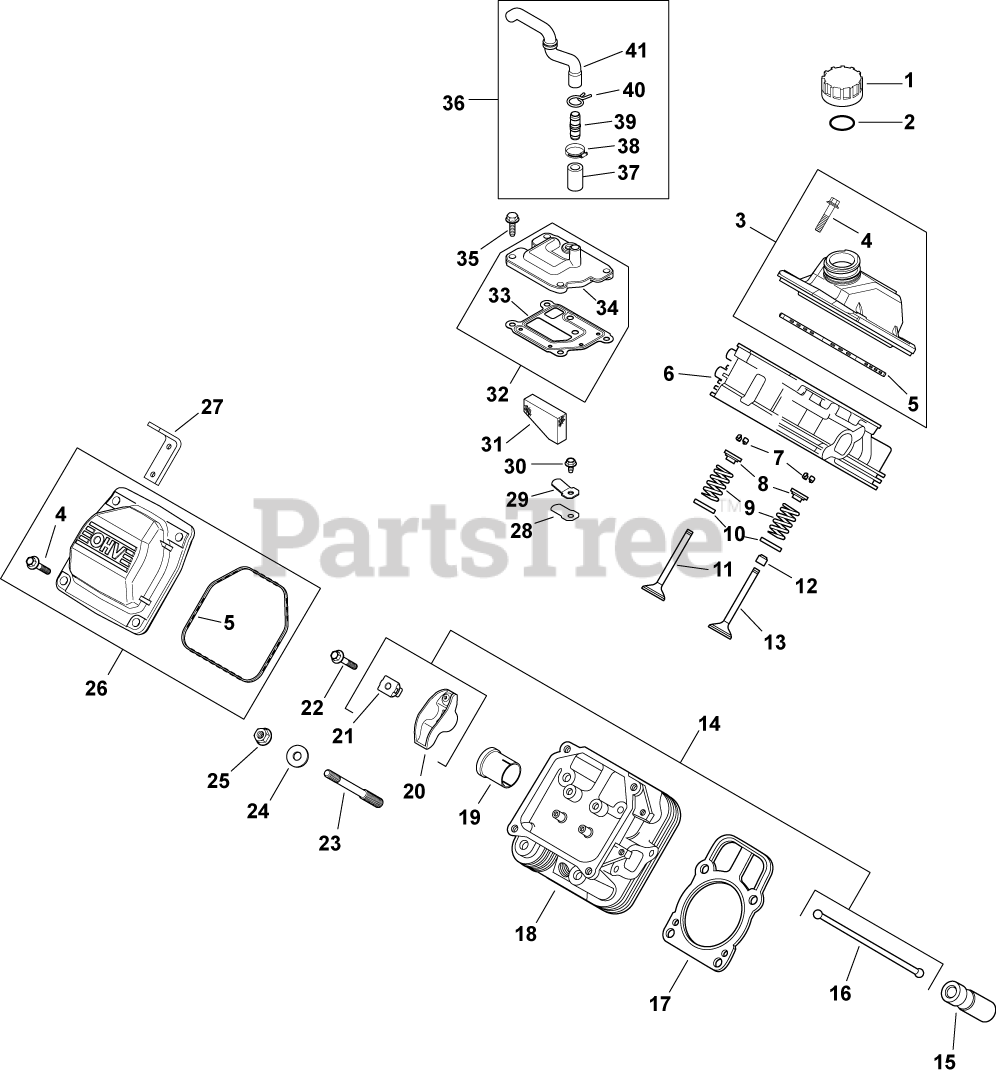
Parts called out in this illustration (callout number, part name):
1	KIT, OIL FILL CAP (YELLOW)
2	O-RING, DIPSTICK
3	KIT, VALVE COVER-OIL FILL
4	SCREW, FLG M6X1.0X30
5	O-RING (YELLOW), VALVE COVER
6	KIT, CYLINDER HEAD #1 - (#24318146S)
7	KIT, RETAINER
8	RETAINER, VALVE SPRING - USE 25 173 28-S
9	SPRING, VALVE
10	RETAINER, SPRING
11	VALVE, EXHAUST (STD) - USE 32 016 01-S
12	SEAL, VALVE STEM - (#2503214S)
13	VALVE, INTAKE (STD)
14	KIT, VALVE TRAIN
15	LIFTER, HYDRAULIC VALVE-USE 25 351 10-S
16	ROD, PUSH
17	CYL HEAD GASKET KIT-USE 24 841 04-S
18	KIT, CYLINDER HEAD #2 USE 24 318 152-S
19	LINER, EXHAUST PORT-USE 24 605 07-S
20	ARM, ROCKER
21	PIVOT, ROCKER ARM
22	SCREW, FLG M6X1.0X34
23	STUD, M8X1.25
24	WASHER, FLAT 8.6 MM
25	NUT, FLG M8X1.25
26	KIT, VALVE COVER-PLAIN
27	STRAP, LIFTING-USE 25 445 03-S
28	REED, BREATHER
29	RETAINER, REED
30	SCREW, FLG THD FRM M5X.8X10
31	FILTER, BREATHER
32	KIT, BREATHER ASSEMBLY
33	GASKET, BREATHER-USE 24 041 67-S
34	COVER, BREATHER -USE 24 033 01-S
35	SCREW,FLG THD FRM M6X1.0X20-(#25086396S)
36	HOSE ASSEMBLY, BREATHER
37	LINE, FLEX FUEL
38	CLAMP, HOSE-USE 25 237 32-S
39	CONNECTOR
40	CLAMP, HOSE (KM)-USE 25 237 31-S
41	HOSE, BREATHER
2401602-S	VALVE, EXHAUST (.25)
2401702-S	VALVE, INTAKE (.25)
